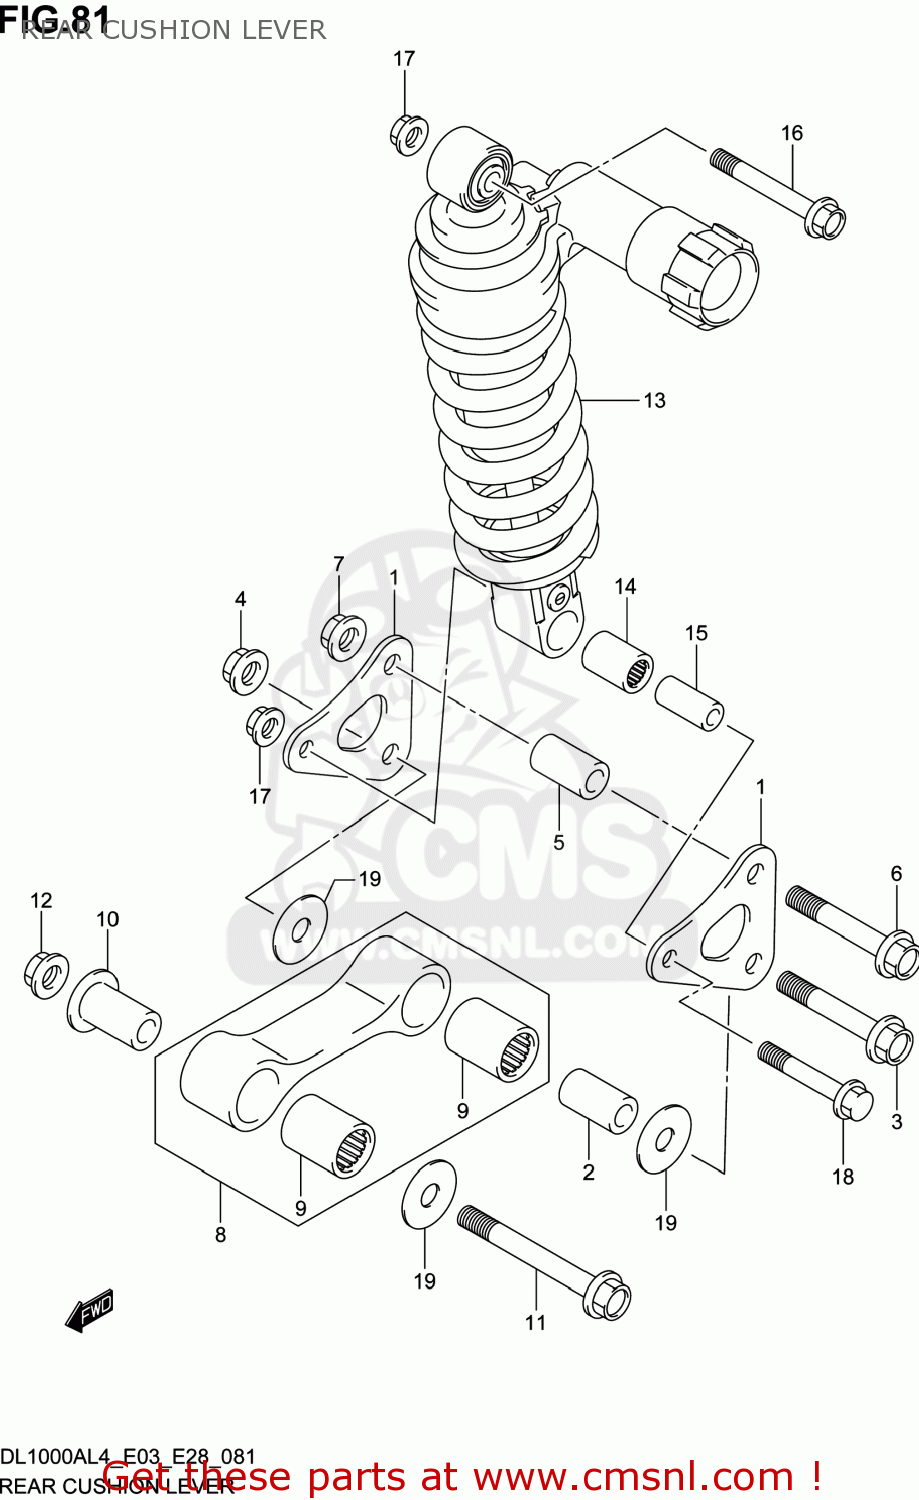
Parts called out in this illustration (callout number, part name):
1	LEVER,REAR CUSHION
2	SPACER,RR CUSHION LEVER FR
3	BOLT,CUSHION LEVER FR
4	NUT
5	SPACER,RR CUSHION LEVER FR
6	BOLT,CUSHION LEVER FR
7	NUT
8	ROD,RR CUSHION
9	BEARING(20X27X32)
10	SPACER,RR CUSHION ROD FR
11	BOLT,RR CUSHION LEVER UPR
12	NUT
13	ABSORBER ASSY,REAR SHOCK(RED)
14	BEARING(17X24X32)
15	SPACER,RR SHOCK ABS LWR
16	BOLT(10X70)
17	NUT
18	BOLT(10X58)
19	WASHER(12X34X1)
